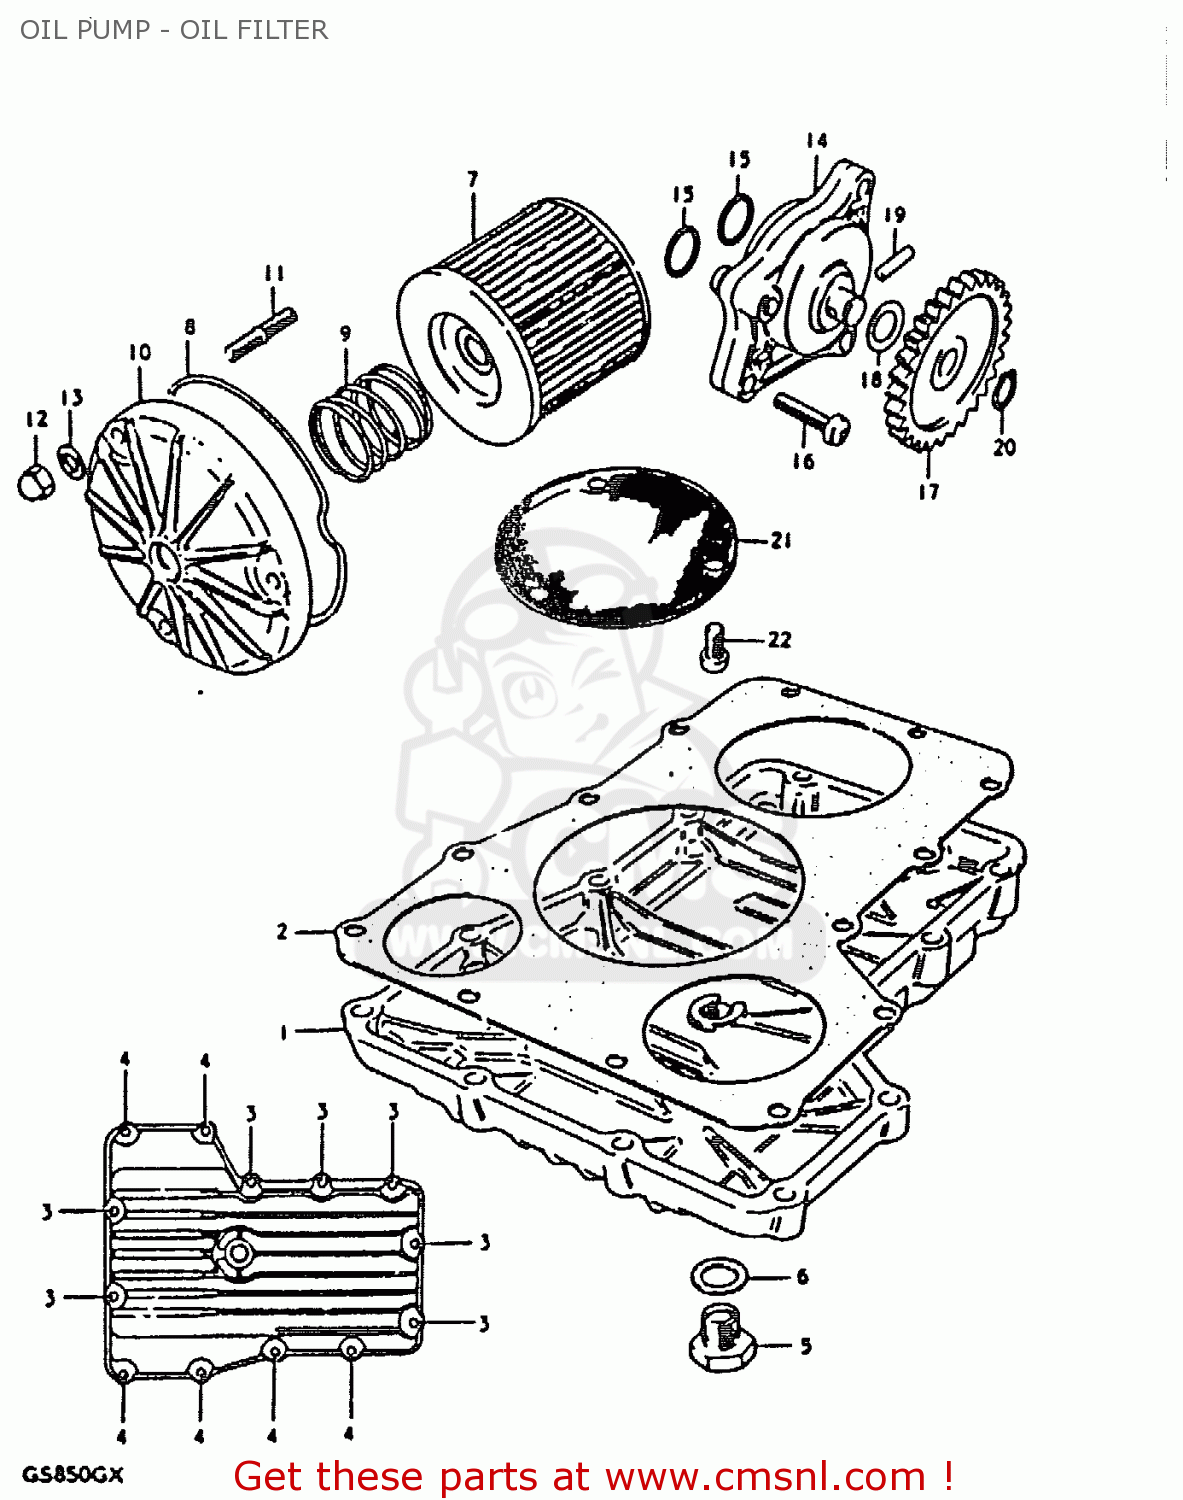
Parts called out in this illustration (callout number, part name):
1	PAN,OIL
2	GASKET,OIL PAN (MCA)
3	BOLT
4	BOLT
5	PLUG
6	GASKET(14X19.2X2) (NAS)
7	ENGINE OIL FILTER SET
8	O RING,OIL FILTER CHAMBER CAP
9	SPRING
10	CAP,OIL FILTER
11	STUD 6X20
12	NUT
13	WASHER
14	PUMP ASSEMBLY,OIL
15	O RING(D:1.9,ID:13)
16	SCREW
17	GEAR,OIL PUMP DRIVEN
18	SHIM
19	PIN(4X15.8)
20	CIRCLIP
21	STRAINER, ENGINE OIL
22	SCREW 6X12
